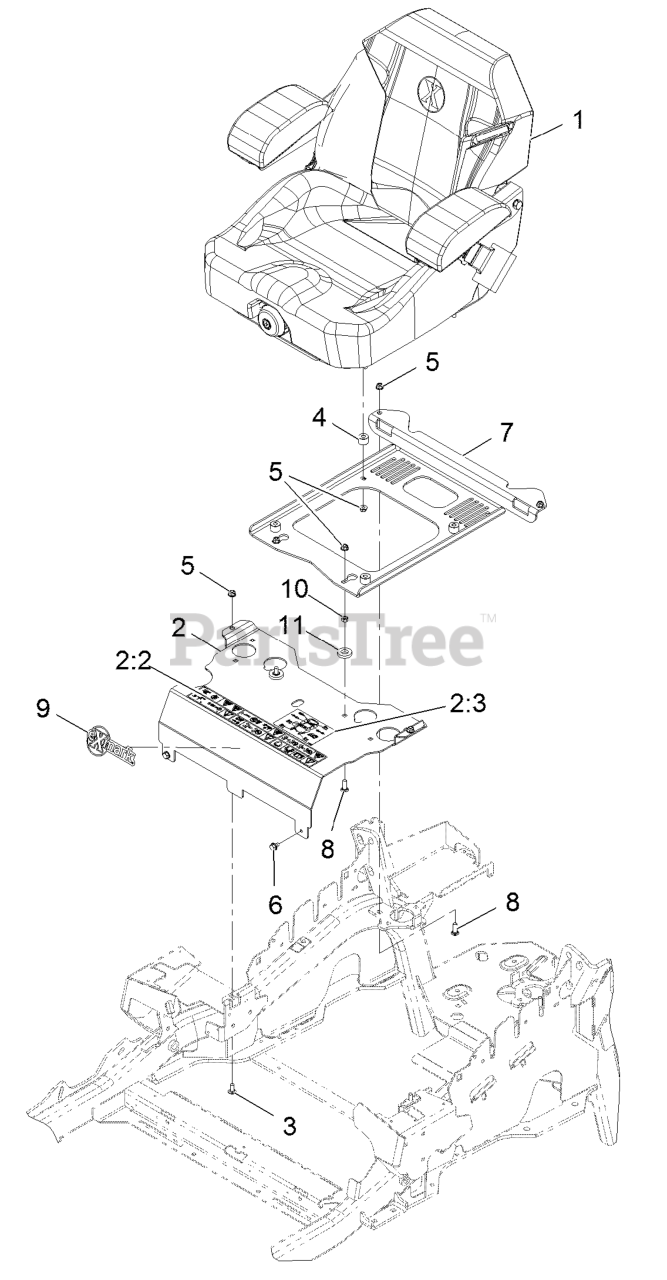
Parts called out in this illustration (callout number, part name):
1	KIT-SUSPENSION SEAT
2	MOUNT-SEAT
2:2	DECAL-CONSOLE
2:3	DECAL-SERVICE AID
3	SCREW-CARR
5	NUT-HF, NI
7	PLATE-SUPPORT, SEAT
8	SCREW-CARR
10	NUT-HEX
